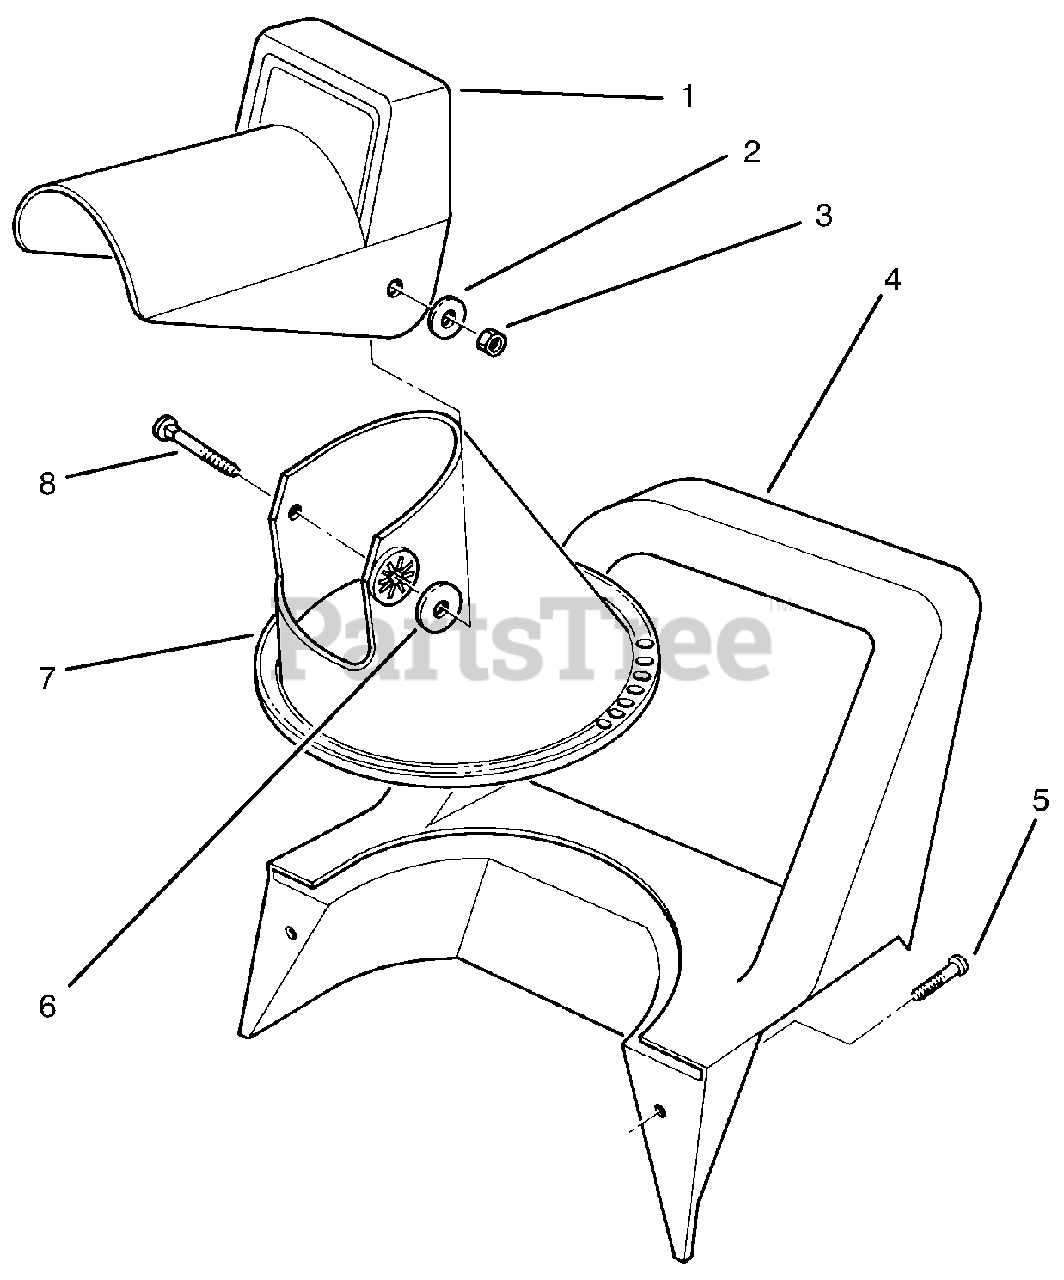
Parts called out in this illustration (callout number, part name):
1	Chute - Deflector
2	WASHER-FLAT
3	NUT-LOCK, NI
4	Handle - Middle
5	SCREW-PPH
6	WASHER-RUBBER
7	Chute - Lower
8	BOLT-CARR
